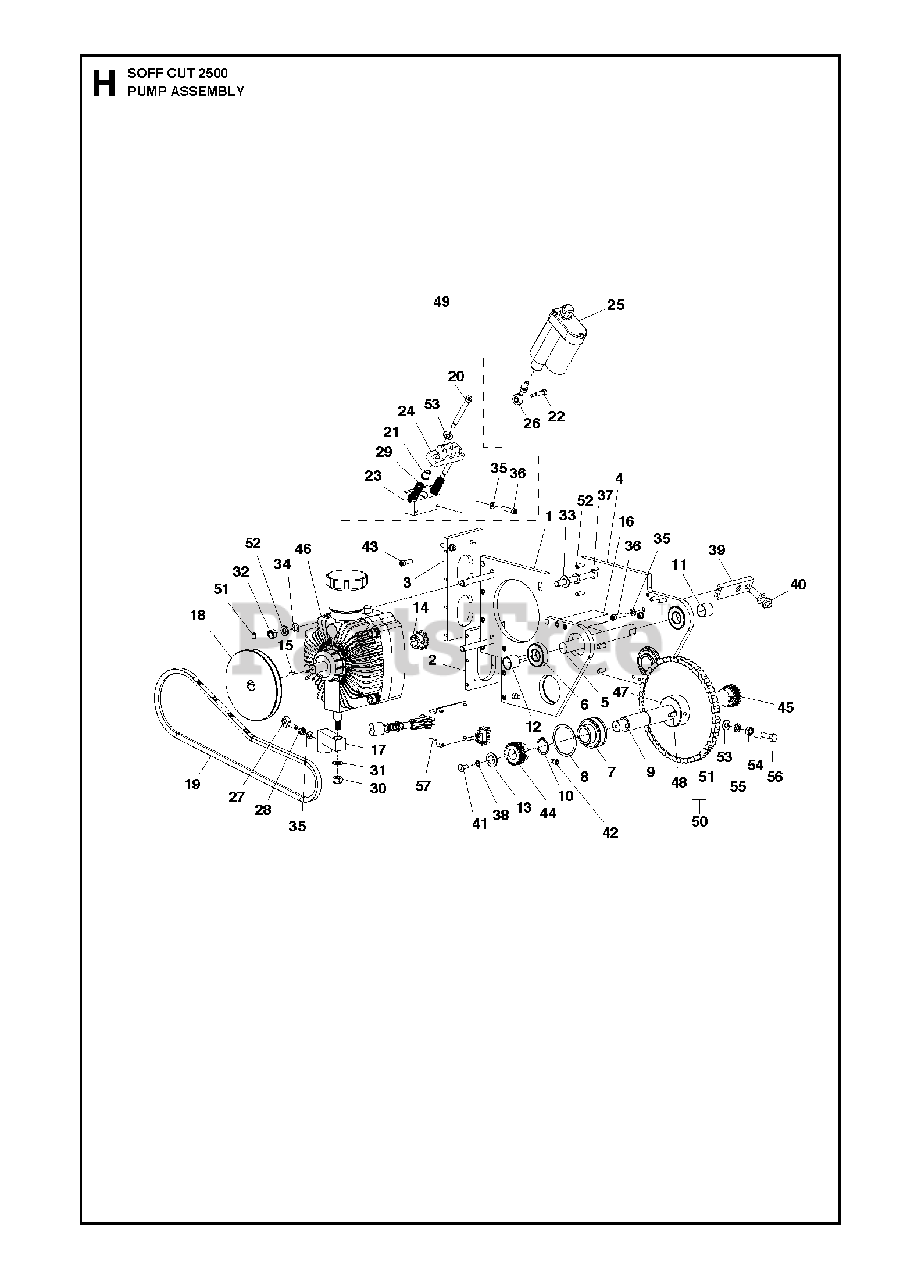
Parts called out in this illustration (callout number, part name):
4	PUMP SUPPORT PLATE LEFT
30	NUT
37	HEX BOLT 3/8-16-3 1/2 CAD GR 5
46	HYDROSTATIC PEDAL ASSY
53	WASHER
